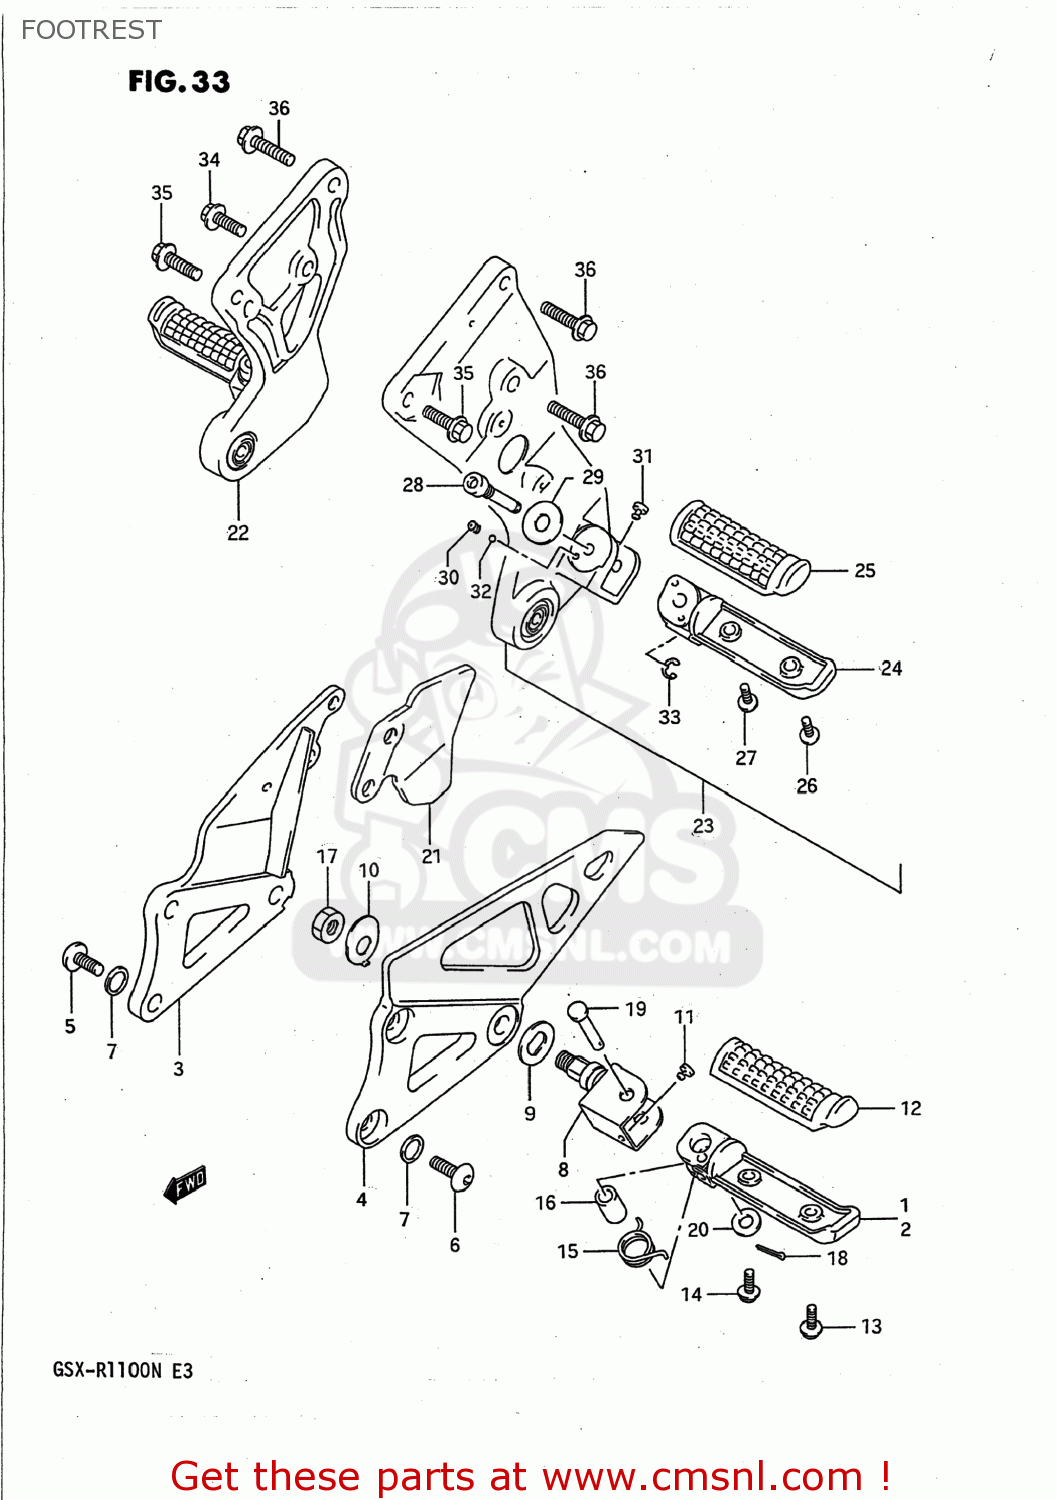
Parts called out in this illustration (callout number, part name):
1	BAR,FOOTREST,R
2	BAR,FOOTREST,L
3	BRACKET,FOOTREST,R
4	BRACKET,FOOTREST,L
5	BOLT,FOOTREST BRACKET
6	BOLT,FOOTREST BRACKET
7	WASHER
8	HOLDER,FOOTREST,RIGHT
9	PLATE,FOOTREST INNER
10	WASHER,FR FOOTREST
11	CUSHION,FOOTREST
12	RUBBER,FOOTREST
13	SCREW
14	SCREW
15	SPRING
16	SPACER(8.1X12X22)
17	NUT 12MM
18	PIN 20X15
19	PIN
20	WASHER(8.5X18X1)
21	GUARD,FRONT FOOTREST,RIGHT
22	FOOTREST ASSY,PILLION,R
23	FOOTREST ASSY,PILLION,L
24	BAR,PILLION FOOTREST,L
25	RUBBER,FOOTREST
26	SCREW
27	SCREW
28	BOLT,PILLION FOOTREST
29	WASHER
30	SPRING
31	CUSHION,FOOTREST
32	BALL
33	E RING 6MM
34	BOLT
35	BOLT
36	BOLT
